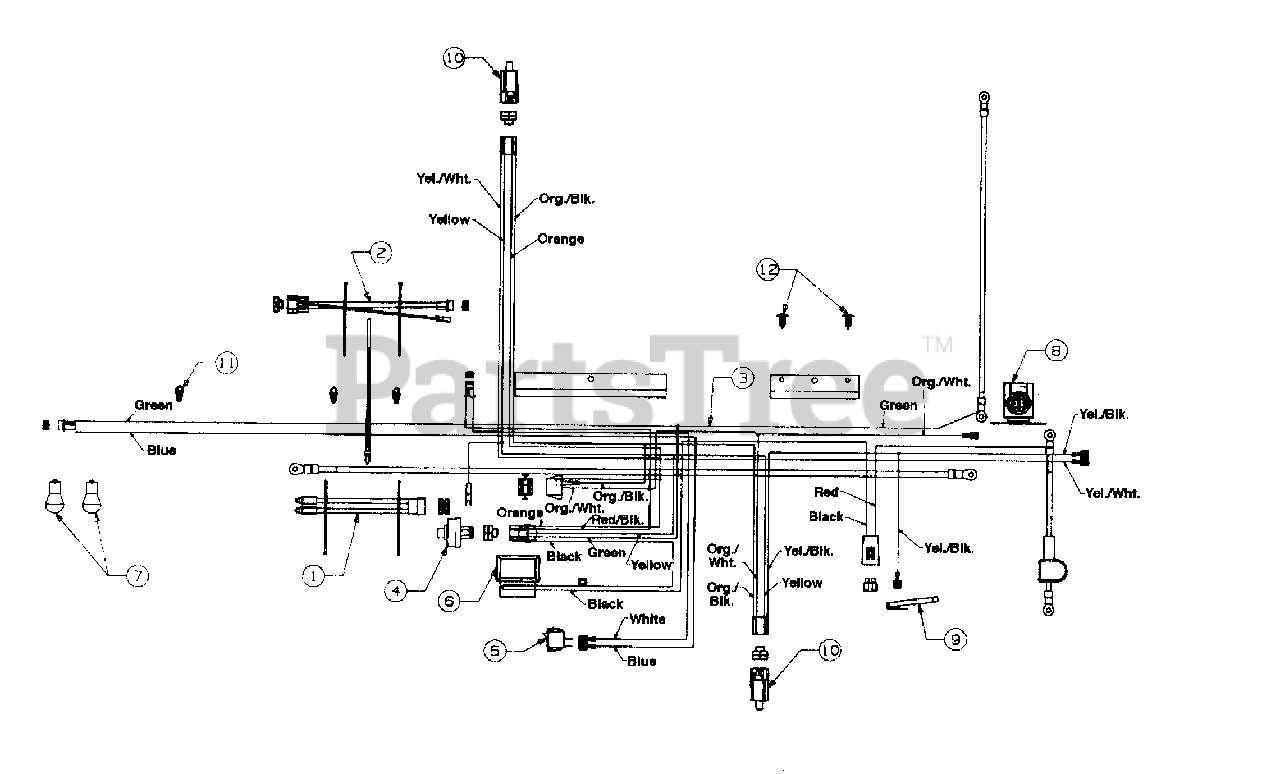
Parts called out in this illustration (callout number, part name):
1	Ratchet
2	Safety Switch
3	Solenoid
4	Bulb (Headlight)
5	Ammeter
6	Light Switch
7	Ignition Switch
8	Wire Harness
9	Wire Harness Adapter
10	Wire Harness (Monitor)
